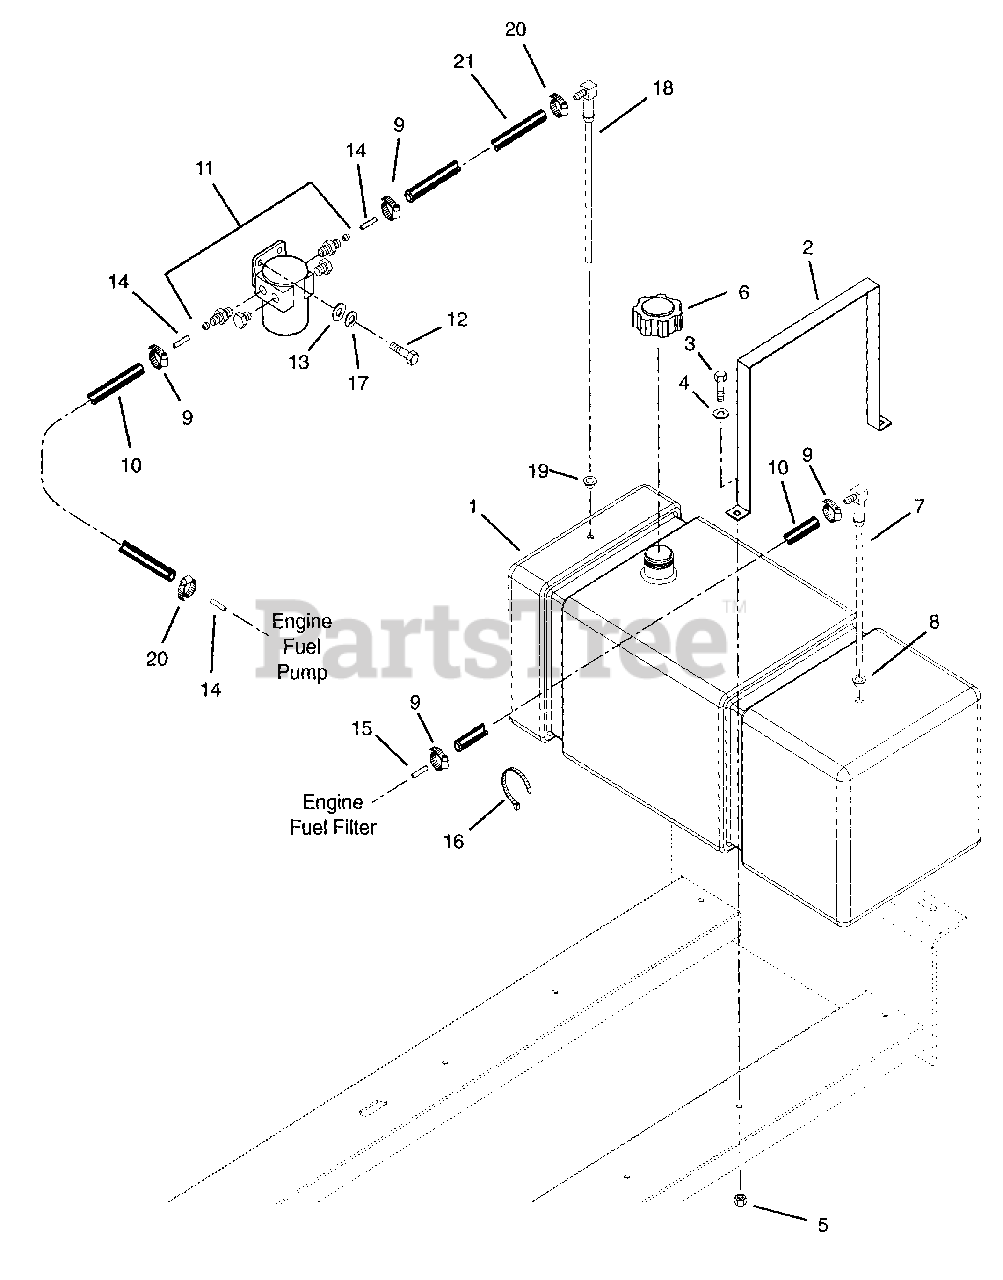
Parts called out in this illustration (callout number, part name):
1	Fuel Tank
2	Fuel Tank Strap
3	Bolt-Hex .375-16 x 1.75 Grade 5
4	Washer-Flat-Steel .438 x 1.00 x .083
5	Nut-Locking-Center .38-16
6	Cap, Fuel Tank
7	Fitting, Tank
8	Bushing
9	Clamp-Hose
10	Gas Line-Bulk
11	Fuel-Pre Filter-Perkins
12	Bolt-Hex .31-18 x 1.25 Grade 5
13	Washer-Flat-Steel .38 x .875 x .083
14	Tubing 5/16" OD x .028 Wall
15	Tubing 1/4" OD x .028 Wall
16	Cable Tie
17	Washer-Lock .31 x .078
18	Fitting, Tank
19	Bushing, Fuel Line Fitting
20	Clamp-Hose
20	Clamp-Hose Worm .44/.78 x .53
21	Gas Line-Bulk 1/4" I.D.
21	Hose-Fuel Line 3/8 in I.D.
